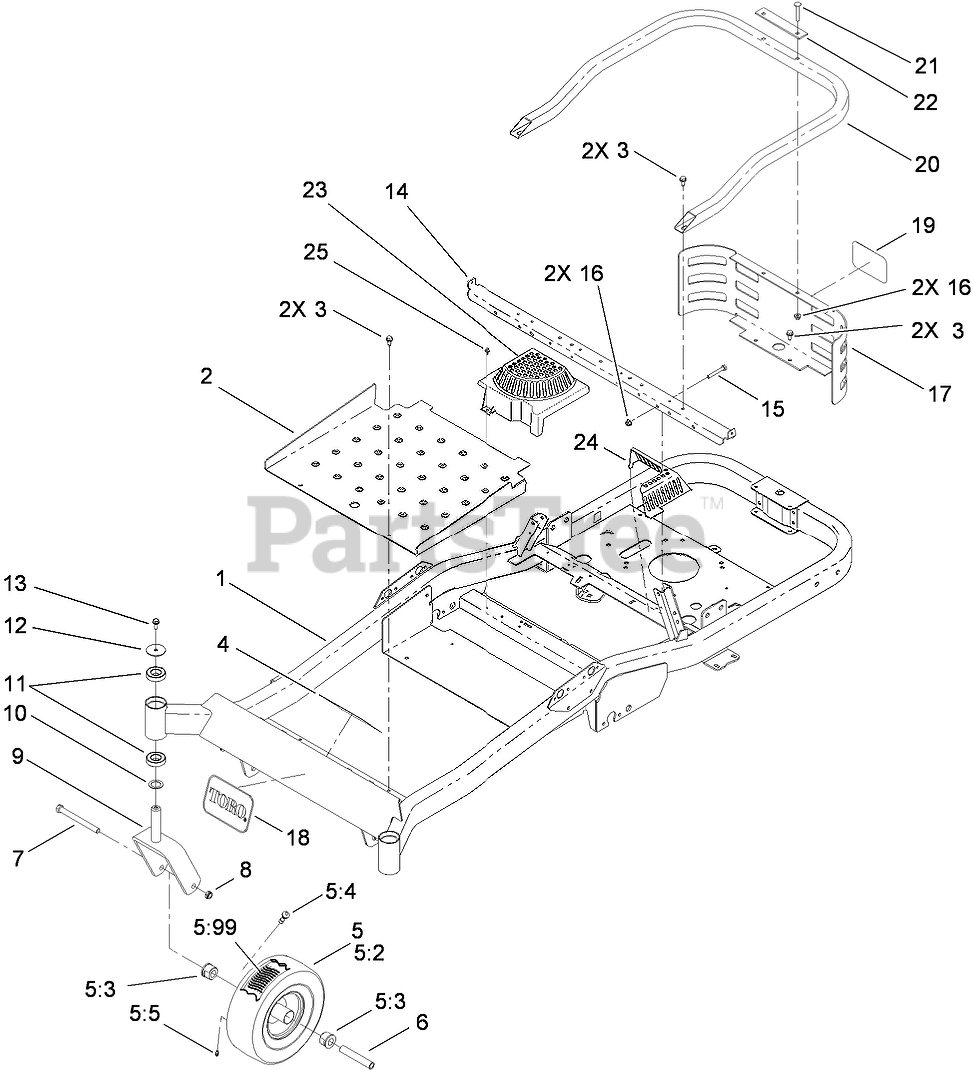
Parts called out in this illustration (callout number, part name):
2	FLOORPAN
3	SCREW-HWHTF
4	DECAL-SAFETY
5	TIRE and Wheel ASM (Kenda)
5:2	TIRE-SMOOTH
5:3	BUSHING-FLANGE
5:4	STEM-VALVE
5:5	FITTING-GREASE
5:99	TUBE-INNER
6	BUSHING-SPANNER
7	SCREW-HH
8	NUT-LOCK, NI
9	CASTER FORK ASM
10	WASHER-THRUST
11	BEARING-BALL
12	WASHER
13	SCREW-HHF
14	SUPPORT-SEAT
15	SCREW-HH
16	NUT-HF, NI
17	GUARD-REAR, SHIELD
18	DECAL
20	GUARD-REAR, TUBE
21	Screw-CARR
22	PLATE-SPACER
23	COVER-FAN, RH
24	COVER-FAN, LH
25	SCREW-HHFTF
